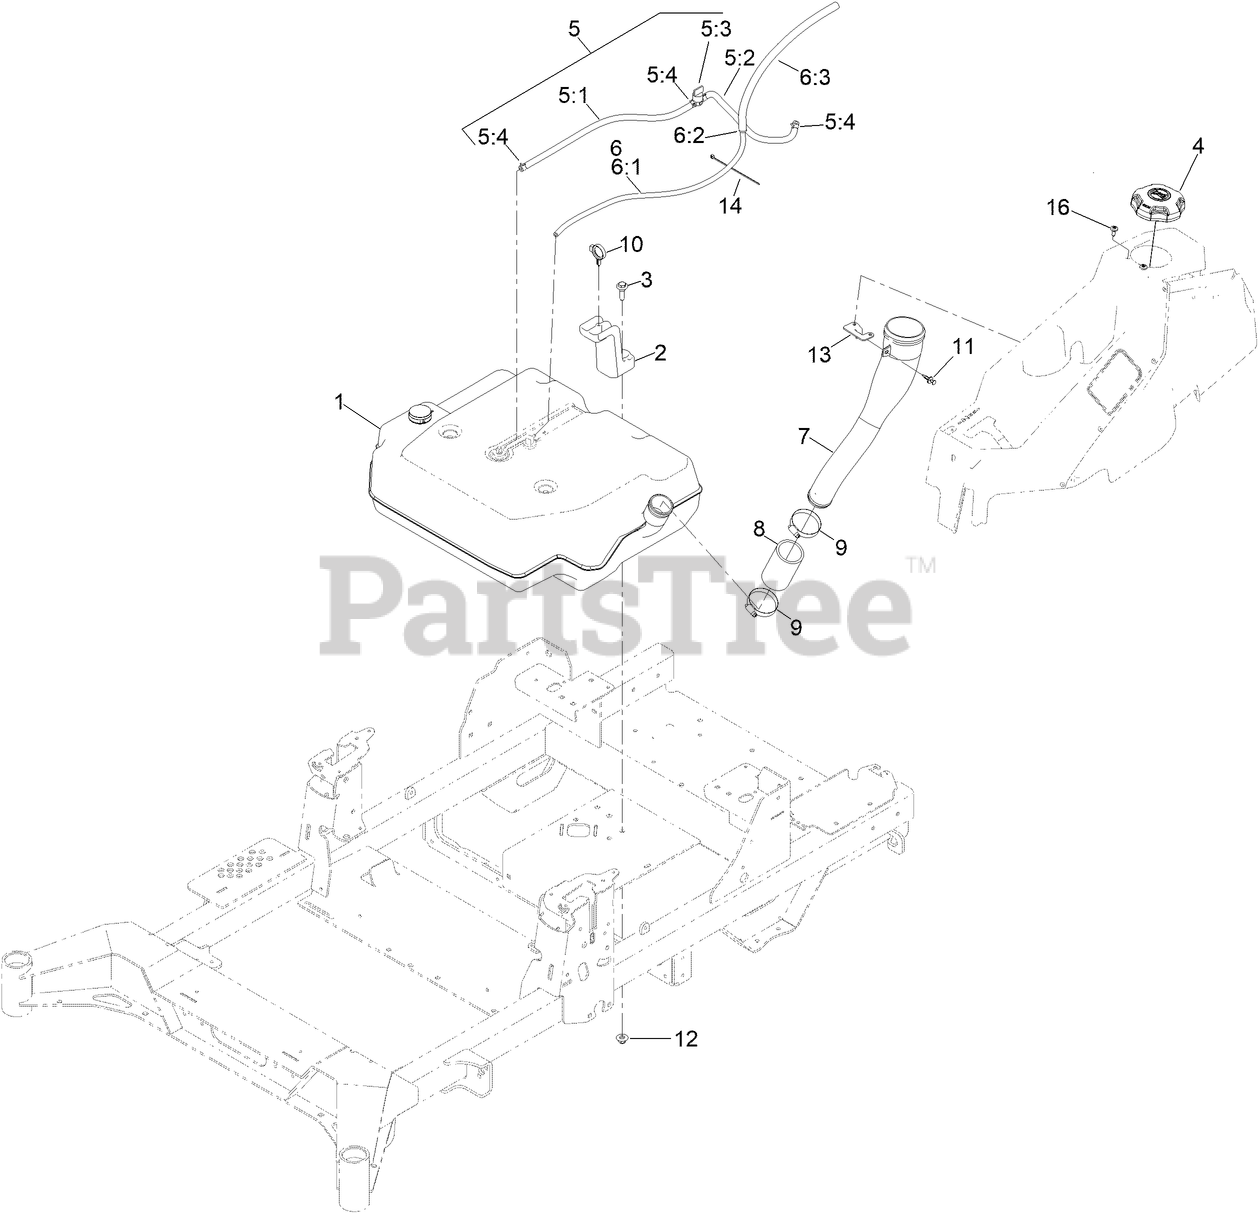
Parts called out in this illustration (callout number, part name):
1	TANK ASM-FUEL
2	RETAINER-TANK, REAR
3	SCREW-SHOULDER, HWH
4	CAP-FUEL, RATCHETING
5	HOSE ASSEMBLY-FUEL/VALVE
5:1	HOSE-FUEL
5:2	HOSE-FUEL
5:3	VALVE-FUEL
5:4	CLAMP-HOSE
6	ASM-FUEL VENT
6:1	HOSE-VENT
6:2	FITTING-ORIFICE, STRAIGHT
6:3	HOSE-FUEL
7	NECK-FILLER, FUEL
8	HOSE-FILLER, FUEL
9	CLAMP-HOSE
10	CLAMP-HOSE
11	RIVET-BLIND
12	NUT-HF, NI
13	BRACKET-MOUNTING, FILL
14	CLIP-EDGE W/TIE, PERPENDICULAR
16	SCREW-SHOULDER
